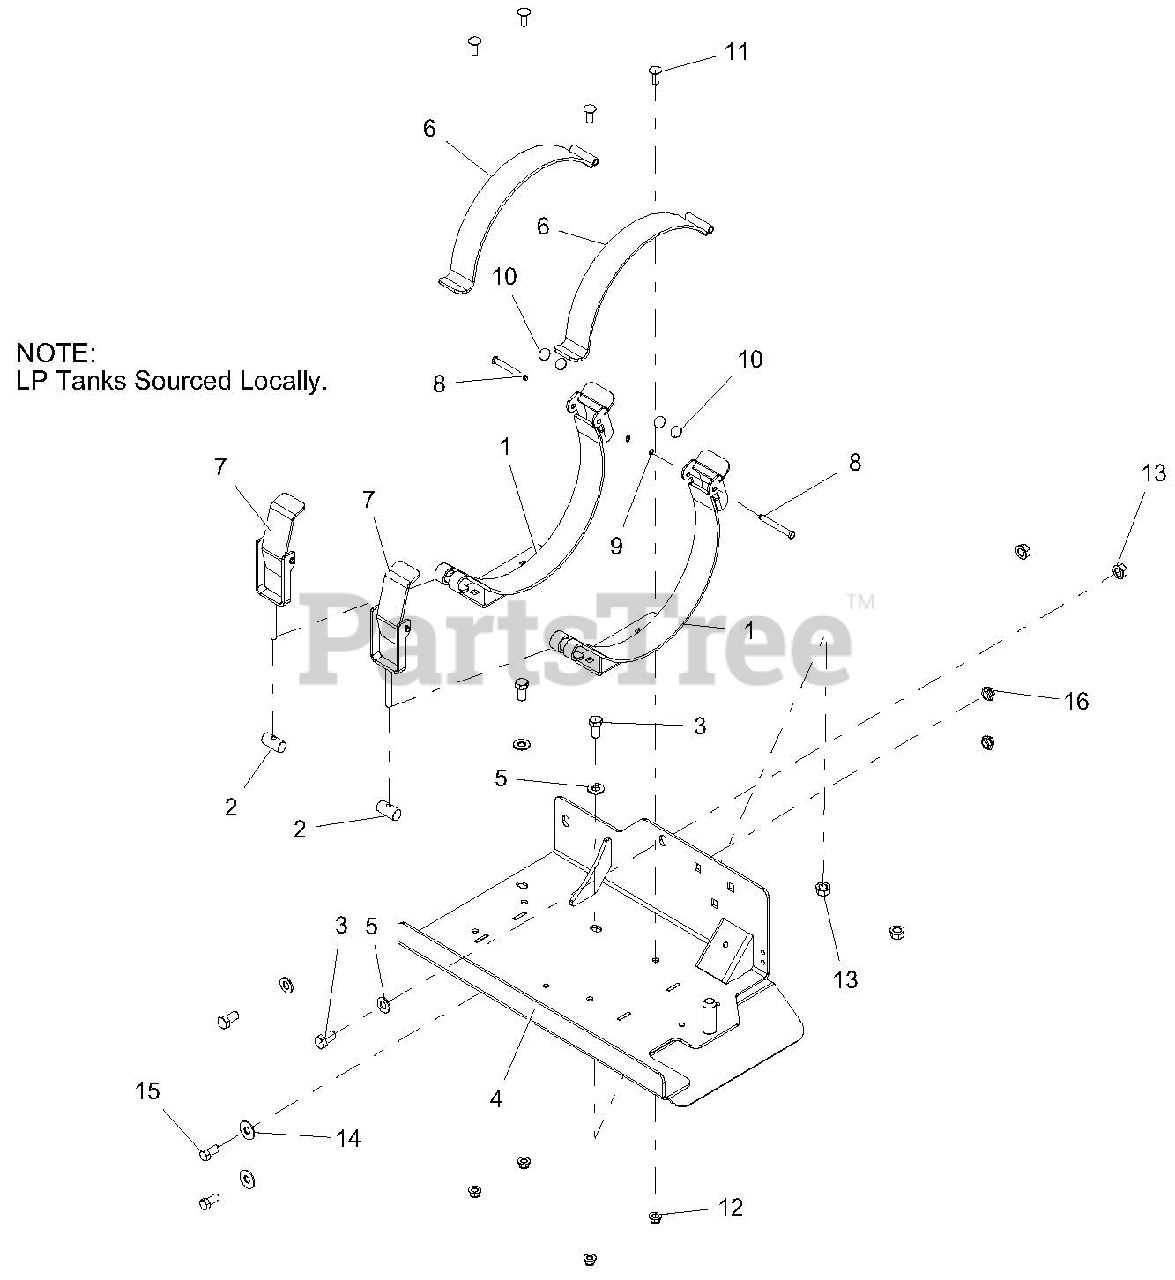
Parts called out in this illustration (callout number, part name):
1	WLDMT, CLAMP LP TANK
2	PIVOT, LP CLAMP HANDLE
3	BLT-HEX .50-13X1.00 GR5 YWZC
4	LH LP TANK MTG W/SAFETY DECAL
5	WSHR-FL-STL.531X1.06X.095YWZC
6	LP TANK CLAMP W/SAFETY DECAL
7	ASM, LP TANK HANDLE CLAMP
8	PIN, LP CLAMP
9	RG-RTNG-EXT .312X.025
10	MAGNET, .75X.060, LP CLAMP
11	BLT-RDHDSQNK .38-16X1.00 G5 YWZC
12	NUT-LK-NYL-FLG .38-16 YWZC
13	NUT, LK-TOP-FLG .50-13 YWZC
14	WSHR-FL-STL..50X1.25X.083 YWZ
15	BLT-HEX .44-14X1.00 GR5 YWZC
16	NUT-LK-NYL-FLG .44-14 YWZC
